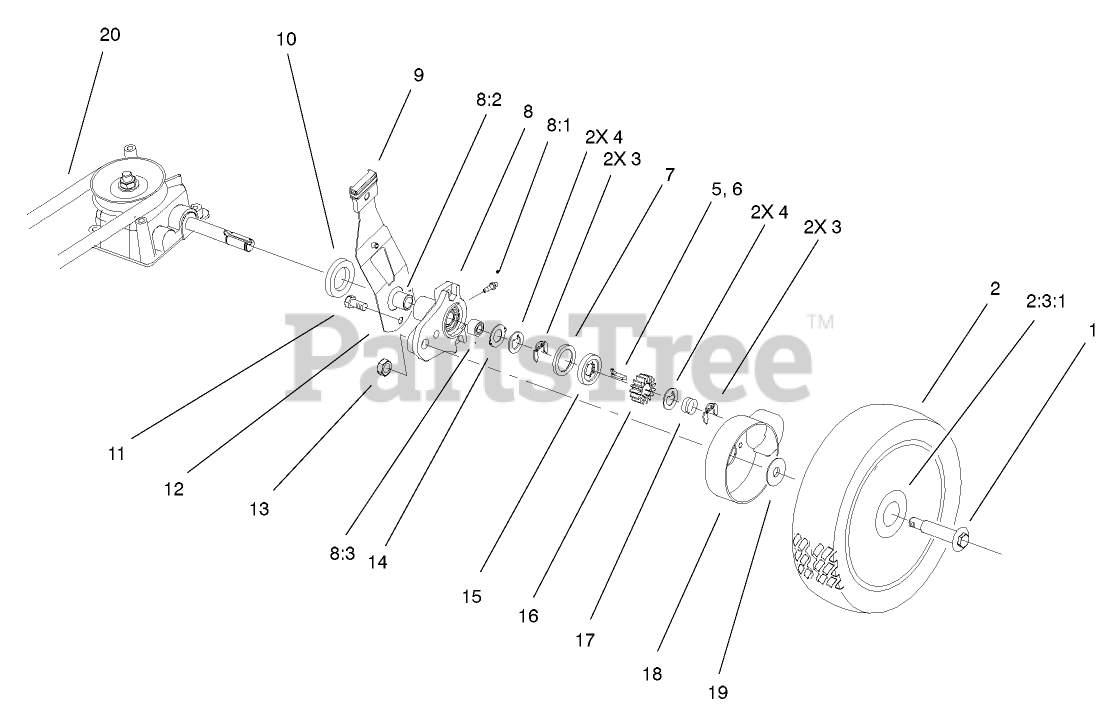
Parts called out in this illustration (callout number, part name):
1	BOLT-SHOULDER
2	WHEEL ASM
2:3:1	BUSHING
3	RING-RETAINING,CLIP
4	WASHER-THRUST, KEYED
5	KEY-ROCKING, RH
6	KEY-ROCKING, LH
7	RING-FRICTION
8	REAR HEIGHT ADJUSTMENT ARM ASM
8:1	FITTING-GREASE
8:2	BUSHING
8:3	BUSHING
9	KNOB-LEVER, HEIGHT ADJUSTMENT
10	SPACER-SHAFT, AXLE
11	SCREW-HWH
12	REAR SPRING ARM ASM
13	LOCKNUT
14	WASHER-ARM, PIVOT
15	WASHER-CLUTCH
16	GEAR-PINION
17	SPRING-COMPRESSION
18	COVER-WHEEL
19	WASHER-STEPPED
20	V-BELT
